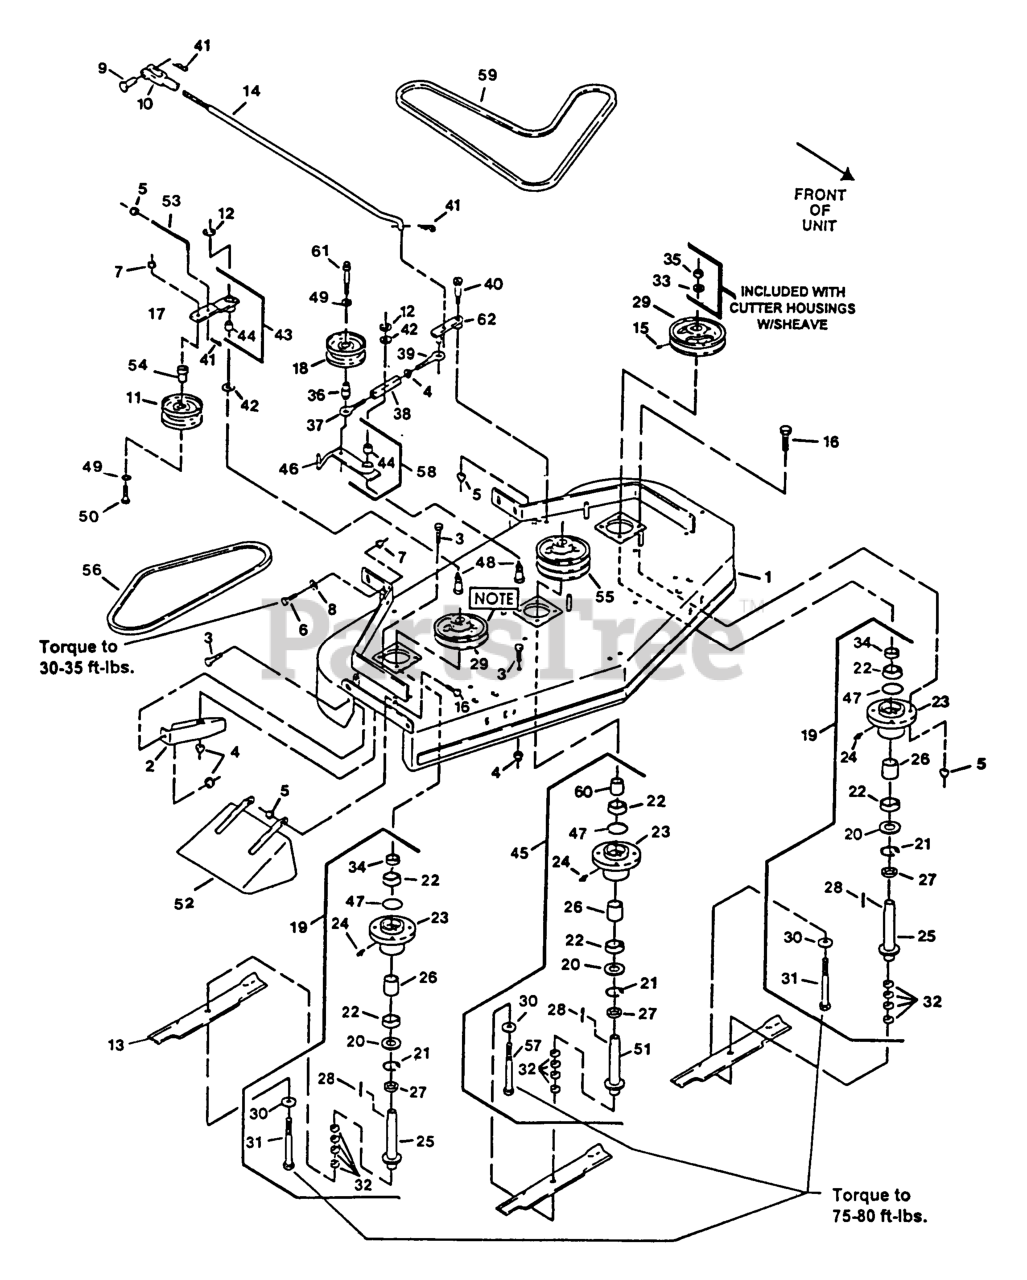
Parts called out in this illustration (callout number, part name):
2	BAFFLE-DOGLEG
9	PIN-CLEVIS
10	YOKE-ADJUSTABLE
11	IDLER,PULLEY
14	ARM-ASSIST, LINKAGE
15	SCREW-SET
17	Arm Weldmt
19	ASM,HOUSING CUTTER
20	SEAL,DUST
21	RING,SNAP WLDS N5000-244
22	BEARING,HD SPINDLE
23	HOUSING,CUTTER
26	SPACER,BRG/BRG
27	SPACER,BEARING &SPINDLE
30	WASHER-SPRING
31	SCREW-CAP, HH
33	WASHER-RETAINER, SHEAVE
36	BUSHING-ENGAGEMENT
37	EYEBOLT-THREAD, LH
38	BODY-TURNBUCKLE
39	EYEBOLT-THREAD, RH
40	BOLT,SHLDR KSKH
41	PIN-COTTER
42	WASHER-SPINDLE
43	ARM WLDMNT W/BUSHING
44	BEARING,POWDERED METAL
52	Chute
53	LINKAGE
54	BUSHING-IDLER
56	BELT,FRONT DECK
57	SCRW,CAP HH 5/8-18X8.5
59	BELT,BLADE DRIVE
60	SPACER,BEARING/SHEAVE
